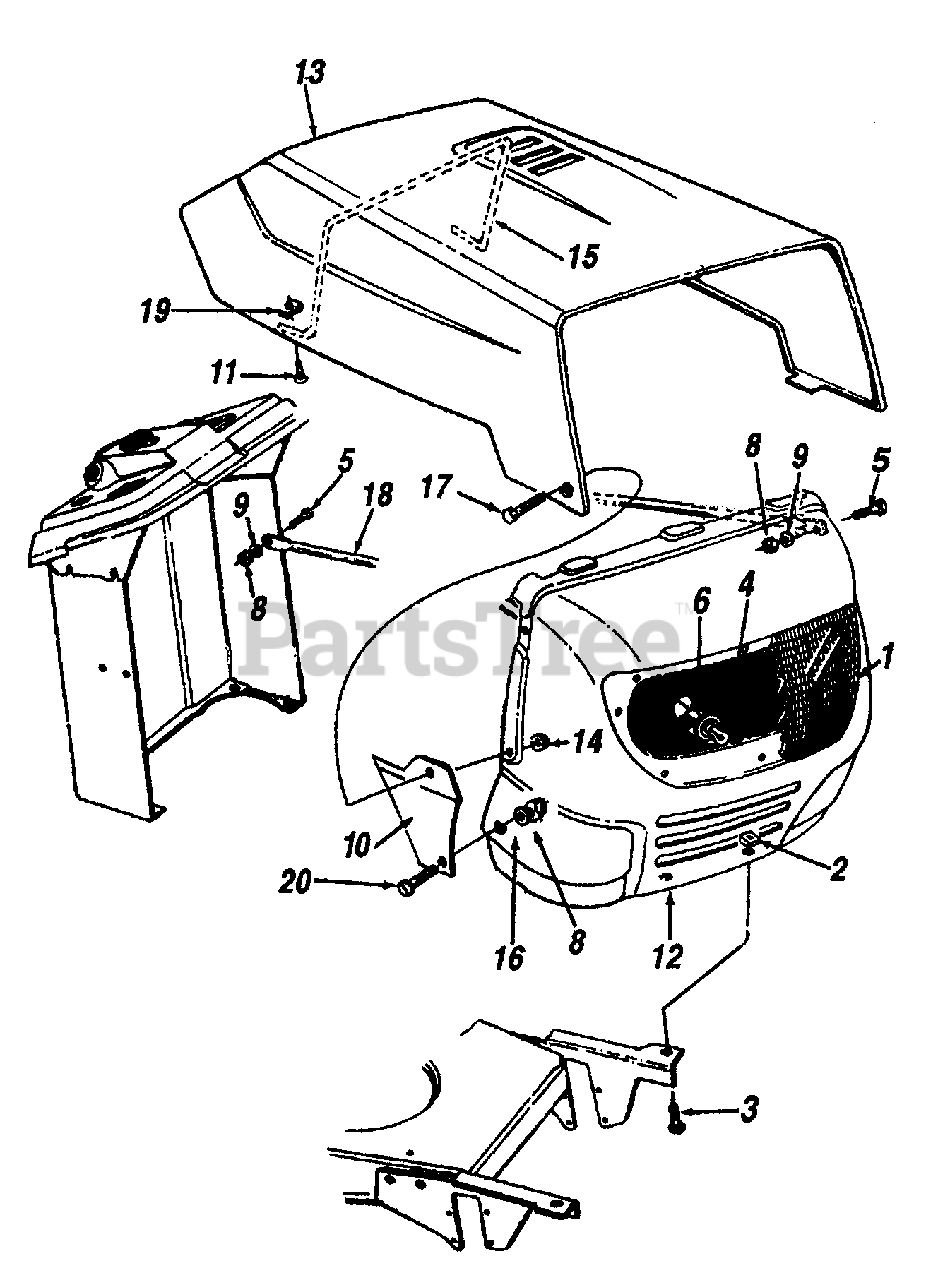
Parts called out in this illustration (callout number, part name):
1	Lens
2	U-Nut 5/16-18 Thd.
3	Hex Bolt 5/16-18 x .75"
4	Bulb
5	Hex Bolt 1/4-20 x .62" Lg.
6	Socket
8	Hex Nut 1/4-20Thd.
9	Lock Washer 1/4" I.D.
15	Hood Spring
16	Bell Washer 1/4" I.D.
17	Shoulder Bolt
20	Pan Hd. Mach. Screw 1/4-20 x .5" Lg.
